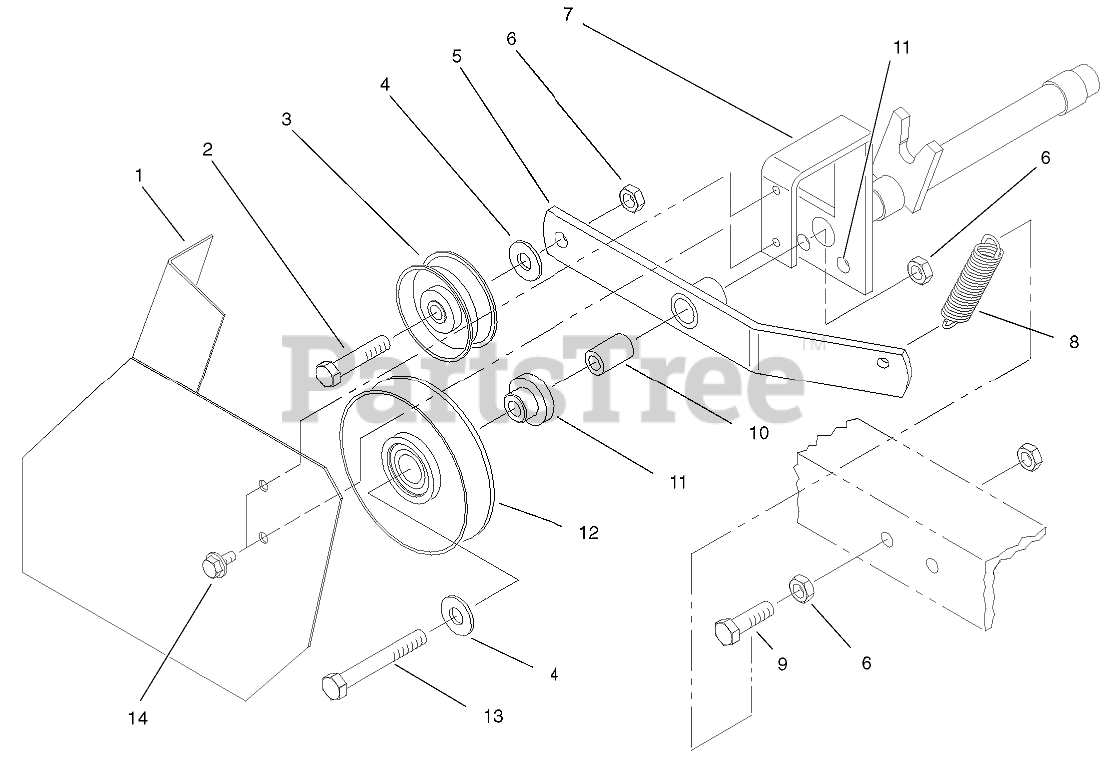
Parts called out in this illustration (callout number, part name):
1	Front Idler Guard ASM
2	SCREW-HH
3	IDLER PULLEY
4	WASHER-FLAT
5	Idler Arm ASM
6	NUT-HEX
7	Support ASM (Welded)
8	SPRING-BRAKE
9	SCREW-HH
10	SPACER
11	SPACER
12	PULLEY-IDLER
13	SCREW-HH
14	SCREW-HWH
